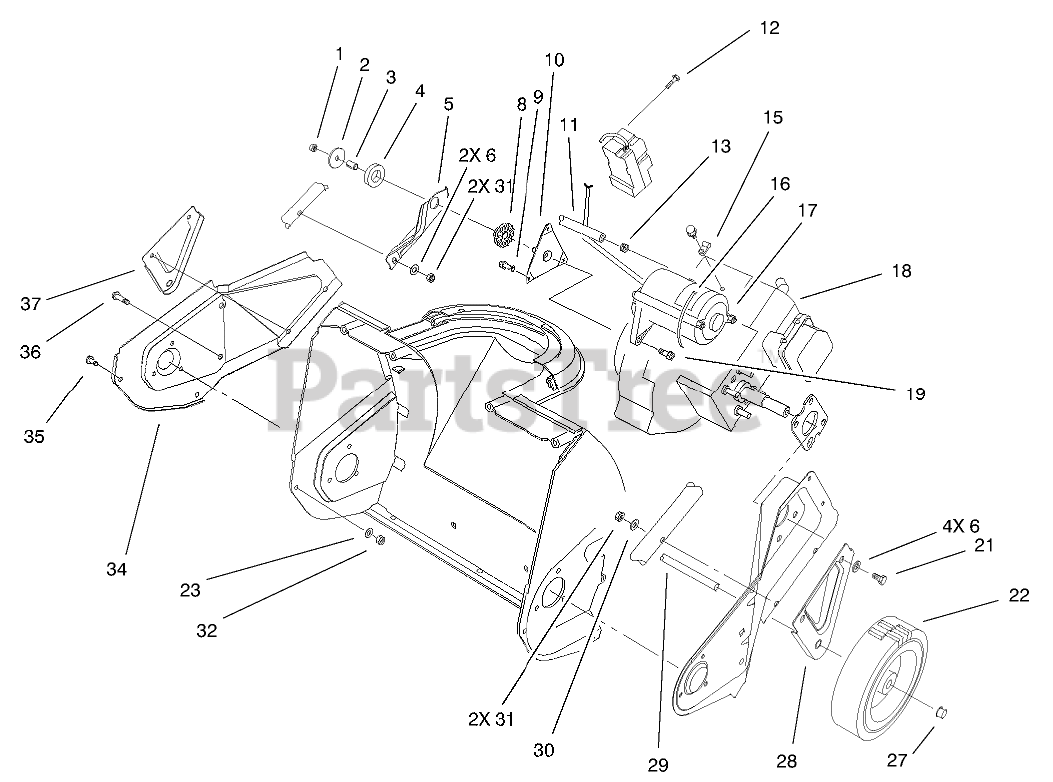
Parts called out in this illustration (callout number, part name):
1	NUT-LOCK, NI
2	WASHER-FLAT
3	SPACER-TUBULAR
4	RING-ISOLATOR
5	BRACKET-SUPPORT, ENGINE
6	WASHER-FLAT
8	BUSHING-ISOLATOR
9	SCREW
10	BRACKET AND STUD ASM
11	LINE-GAS
12	Screw-Plastite (only on: 38182)
13	CLAMP-HOSE
15	Clamp (only on: 38182)
16	Tie-Cable (only on: 38182)
17	Starter ASM (120 Volt)(Service)(only on: 38182)
19	Screw-Mtg Torx (only on: 38182)
21	SCREW-HH
22	WHEEL
23	WASHER-FLAT
27	RETAINER-PUSH ON
28	BRACKET-WHEEL, LH
30	WASHER
31	NUT-LOCK, NI
32	NUT-LOCK, NI
34	PLATE-SIDE, RH
36	SCREW-PLASTIC
37	BRACKET-WHEEL, RH
